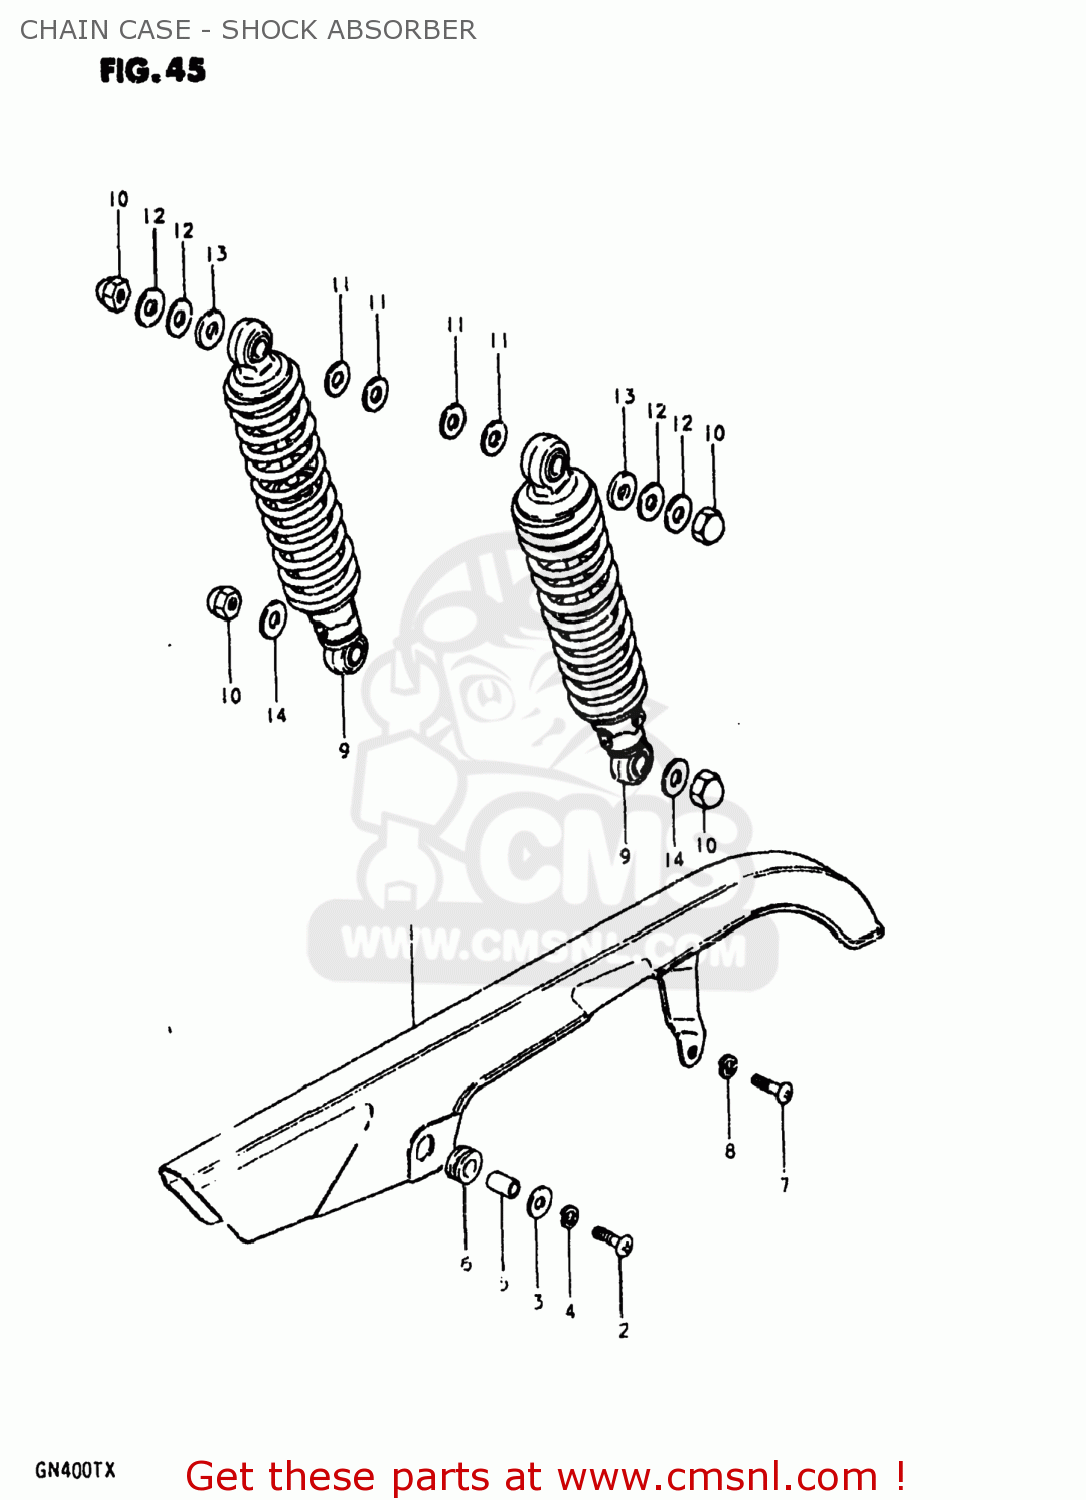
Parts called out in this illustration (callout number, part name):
1	CASE,CHAIN
2	SCREW
3	WASHER (6.5X20X1.2)
4	LOCK WASHER
5	SPACER (7X9X7)
6	CUSHION
7	SCREW
8	LOCK WASHER
9	ABSORBER ASSEMBLY,REAR SHOCK
10	NUT, LOWER LH
11	WASHER
12	WASHER
13	WASHER(10.5X24X3.2)
14	WASHER
